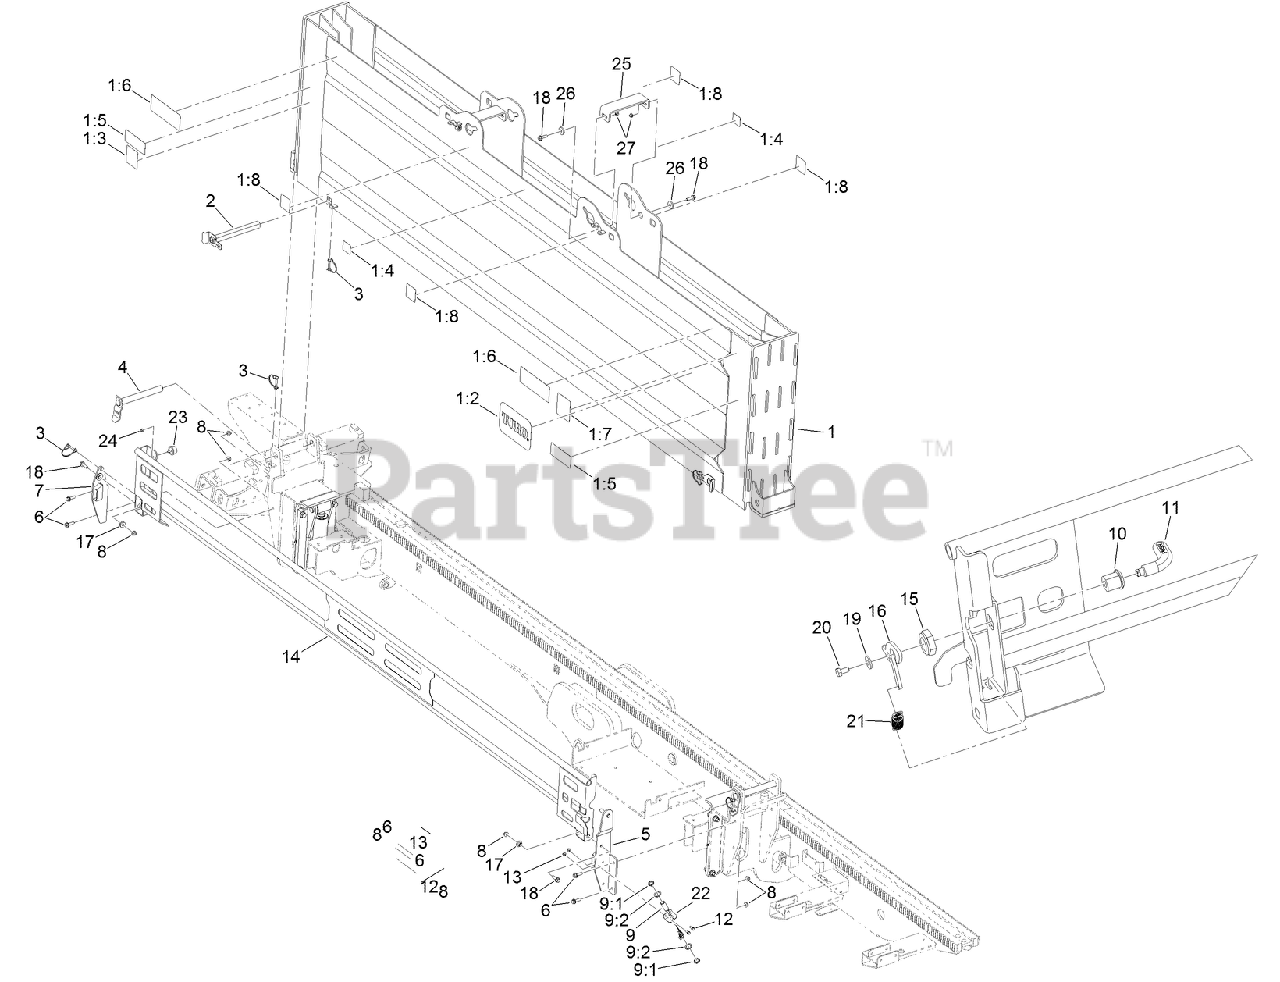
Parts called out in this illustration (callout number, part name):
1	ROD BOX ASM
1:2	DECAL
1:3	DECAL-WARNING
1:4	DECAL-WEIGHT, ROD BASKET
1:5	DECAL-WARNING
1:6	DECAL-DANGER, HAZARDOUS AREA
1:7	DECAL-DANGER, SHOCK
1:8	DECAL-LIFT HERE
3	PIN-HITCH
5	ROD-LOAD, REAR
6	SCREW-HHF
7	ROD-LOAD, FRONT
8	NUT-HF, NI
9	PROXIMITY SWITCH ASM
9:1	NUT-HEX
9:2	WASHER-LOCK, INTERNAL TOOTH
10	HOUSING-LATCH
11	HANDLE-LATCH
12	SCREW-HHF
13	NUT-FLANGE, NI
14	HANDLE-LOAD, PIPE
16	CAM-HOOKED
17	HUB-PIVOT
18	SCREW-HHF
19	WASHER-FLAT
20	SCREW-HH
21	SPRING
22	BRACKET-SENSOR
23	BUMPER
24	NUT-LOCK, NI
25	PLATE-GUARD, PIPE
26	SPACER
27	NUT-HF, NI
